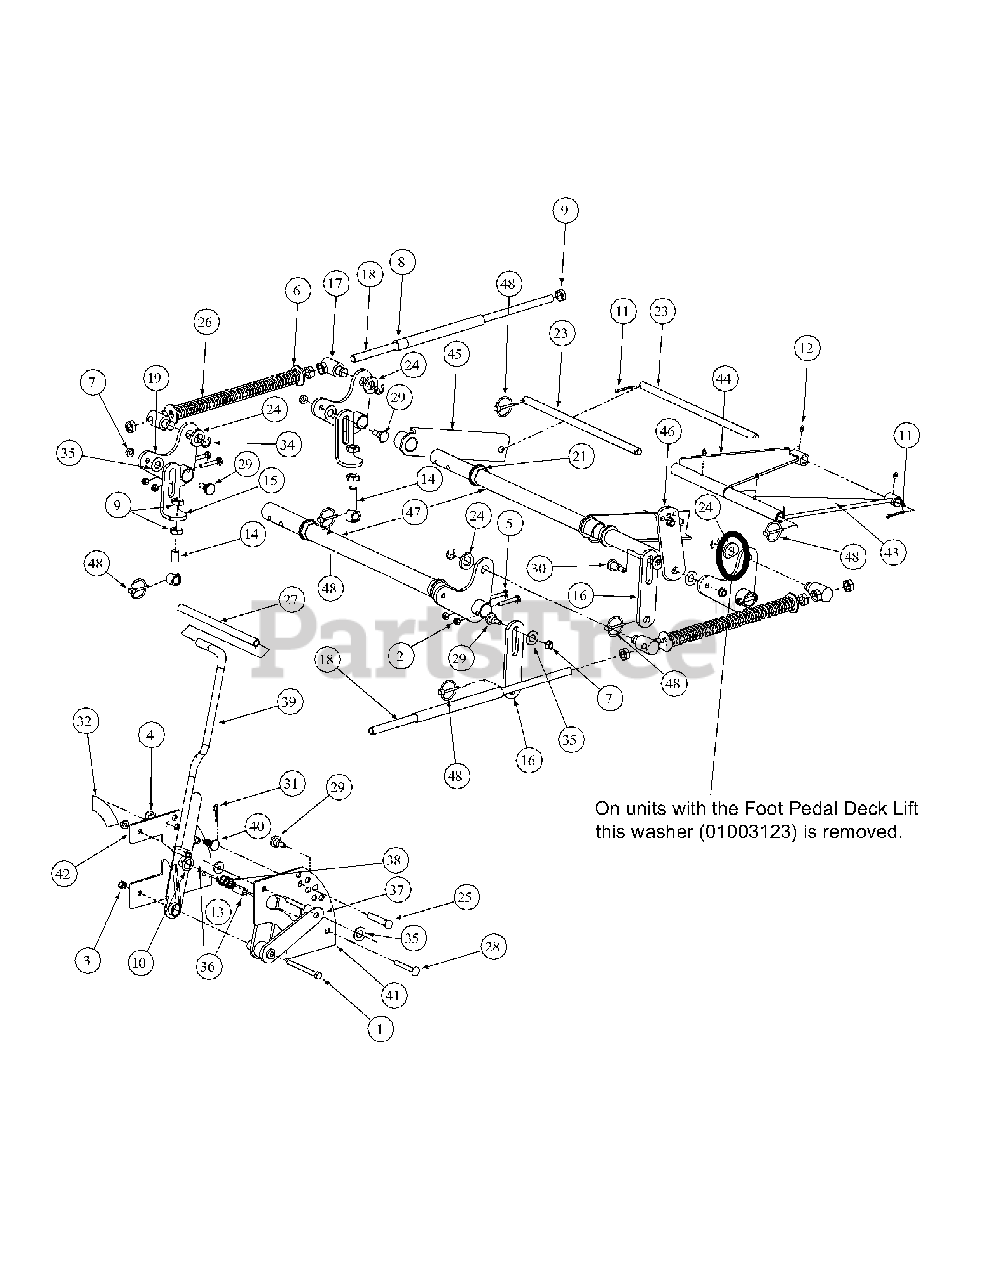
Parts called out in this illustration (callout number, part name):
1	Hex Cap Screw, 3/8-16, 3.75
2	Nut, 5/16-18, Nylock
3	Nylock Insert Lock Nut, 3/8-16
4	Nylock Insert Lock Nut, 1/2-13
5	Socket Head Capscrew, 5/16-18 x 2
6	Flat Washer, 5/8
7	Hex Nut, Flange Lock, 3/8-16
8	PVC Hose, 5/8 ID x 13/16 OD x 8"
9	Jam Nut, 5/8-11
10	Flat Washer, .06, .776, 1.25
11	Cotter Pin, 3/16 x 1-1
12	Grease Fitting, 1/4-28 x 3/16
13	Idler Washer
14	Eye Bolt, 5/8ID
15	Eye Bolt Mount Link, 5/8 ID
16	Deck Link
17	Ferule Lift
18	Lift Connector Rod
19	Bellecrank Weldment Lift
21	Hex Flange Bearing, 1.25 ID
23	Front Lift Link, Rod Mount
24	Spacer, .812 ID x .268 Lg.
25	Clevis Pin, .500 Dia. x 2.625 Lg.
26	Lift Compression Spring
27	Lift Handle Grip
28	Carriage Bolt, 3/8-16, 2.75
29	Shoulder Screw, 0.625 OD x .437 Lg.
30	Shoulder Screw, 0.625 OD x .830 Lg.
31	Cotter Pin, .148 x 3.00
32	Decal Height Indicator
34	E Clip, 3/4 Dia.
35	Nylon Flat Washer, 5/8
36	Spacer, .39 ID x .63 OD x 1.442
37	Lift Pivot Assembly
38	Lift Handle Spring
39	Lift Handle Assembly
40	Shoulder Screw, 5/8 OD x 0.264
41	Outer Lift Index Plate
42	Inner Lift Index Plate
43	Bearing Lift Brace Assembly, Right Hand
44	Bearing Lift Brace Assembly, Left Hand
45	Front Frame Strut Assembly
46	Lift Link Adjustment
47	Lift Shaft Holder
48	Linch Pin, 3/16
